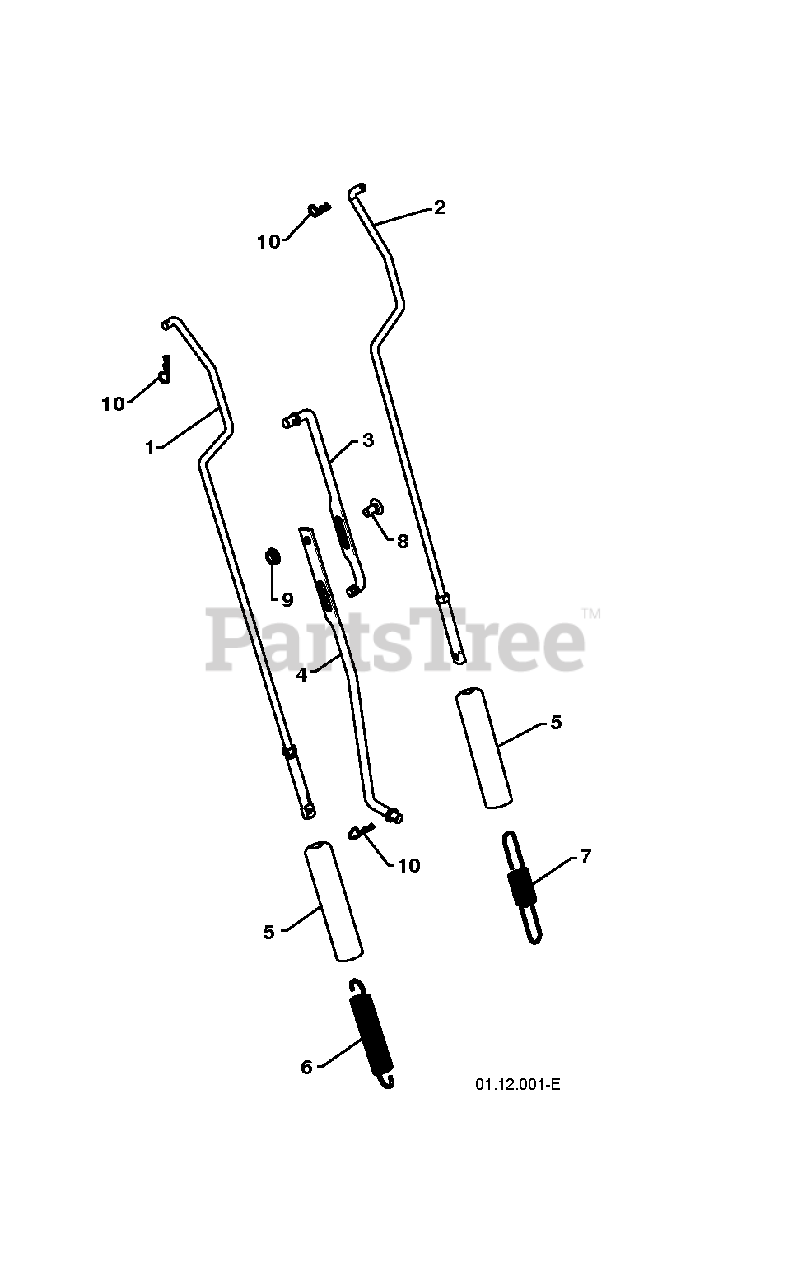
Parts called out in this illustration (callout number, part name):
1	ROD.ASM.IMPELLER
2	ROD.ASM.TRACTION
3	ROD, UPPER SPEED CONTROL
4	ROD, LOWER SPEED CONTROL
5	SLEEVE, SPRING
6	SPRING, AUGER CONTROL
7	SPRING, TRACTION DRIVE
8	BOLT
9	NUT.FLANGE.5/16
10	SPRING RETAINER
